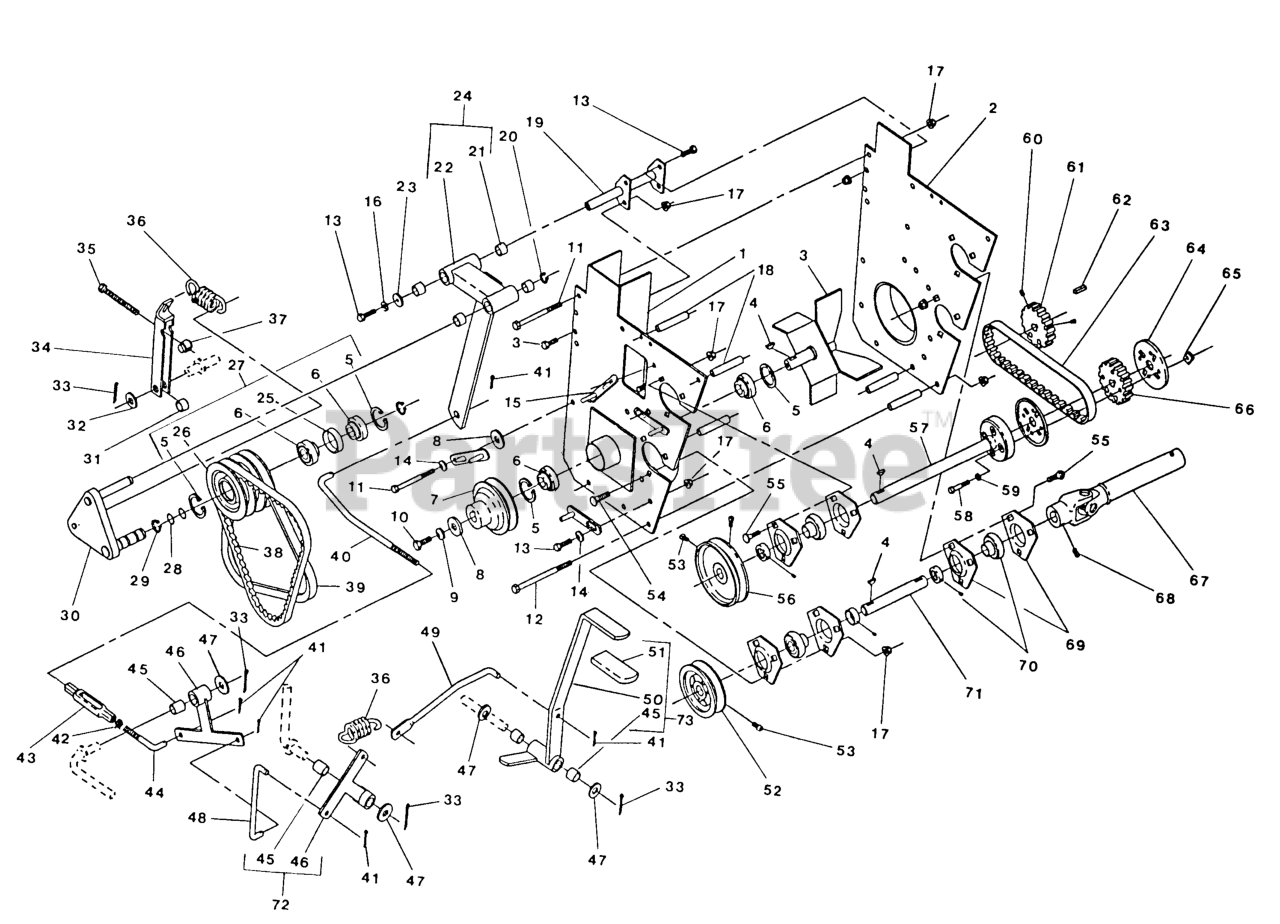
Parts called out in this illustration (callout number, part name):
2	WLD,PANEL FRONT
4	KEY-WOODRUFF
6	BEARING
12	SCREW-HH
14	WASHER-SPRING
16	WASHER-LOCK
22	Control Wldm't - Tmfr. Sheave
24	CNTRL ASSY,TRANS SHV
25	SPACER,TRANSFER BEARING
28	O-RING,
36	SPRING,BELT TENSION
37	SWIVEL,BELT TENSION
38	BELT,B SIZE 43.5
39	BELT,SECONDARY DRIVE
40	ROD,PTO LOW RH THD
44	ROD,PTO RH LOW LH THD
45	SLEEVE-BEARING
49	ROD,PTO UPPER
51	GRIP-LEVER
52	SHEAVE,5.5 B
53	SCREW-SET
56	SHEAVE,7 B
59	WASHER-LOCK
63	BELT,DRIVE POSITIVE
65	NUT,RETNR UTYP 1/4-20
69	HOUSING-FLANGE
70	BEARING,W/COLLAR
71	JACKSHAFT,PTO
